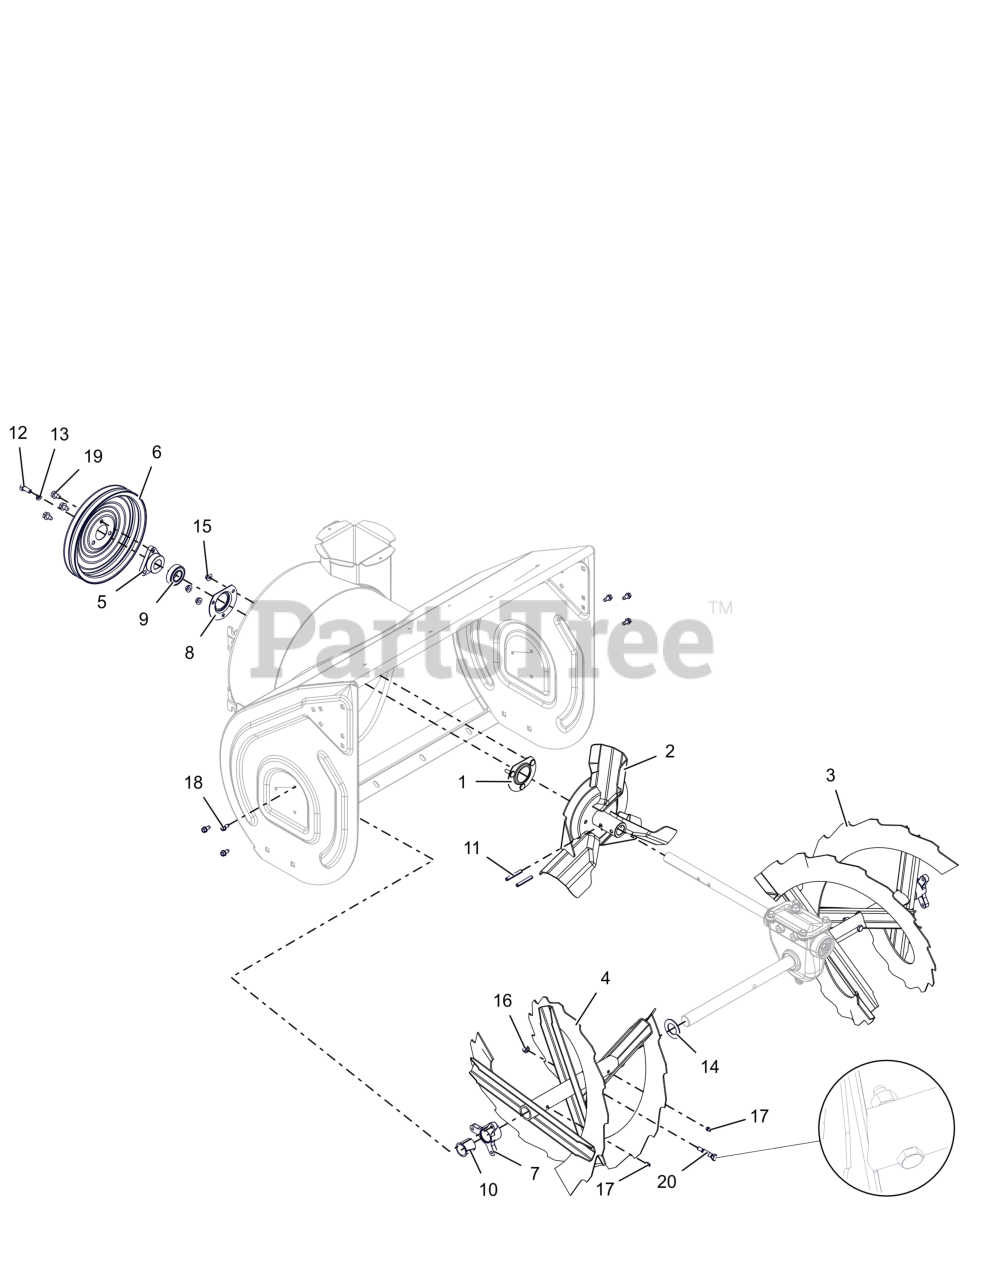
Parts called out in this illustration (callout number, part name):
1	BEARING FLANGE
2	IMPELLER, 3 BLADE-14"
3	RAKE, LH-28"(1 ID X 15.75 OD)
4	RAKE, RH-28"(1 ID X 15.75 OD)
5	PULLEY HUB, D-BORE .87 PRO
6	PULLEY, SPIN FORM DUAL GROOVE
7	BUSHING, RAKE SHAFT 1"
8	BEARING FLANGE
9	BRG-BALL .876X1.75X.50 RSTFP
10	BSHG-FLG SPLIT NYLINER 1.0" HP
11	PIN-ROLL .250X1.75
12	BLT, HEX .31-24X.750 G5 ZCC
13	WSHR, LK-HVY .312X.097 ZCC
14	WSHR- FLT 1.010X1.755X.062 ZCC
15	NUT-LK-CTR-FLG .25-20 ZC120
16	NUT,LK-CTR .31-18 GA ZCC
17	ZERK,FITTING .25X.125 DRIVE IN
18	SCR-TAP .25-20X.50 HWH ZCC
19	SCR,TAP .312-18X.50 HWH TR ZCC
20	SHEAR BOLT SERVICE ASSEMBLY (INCLUDES NUT)
